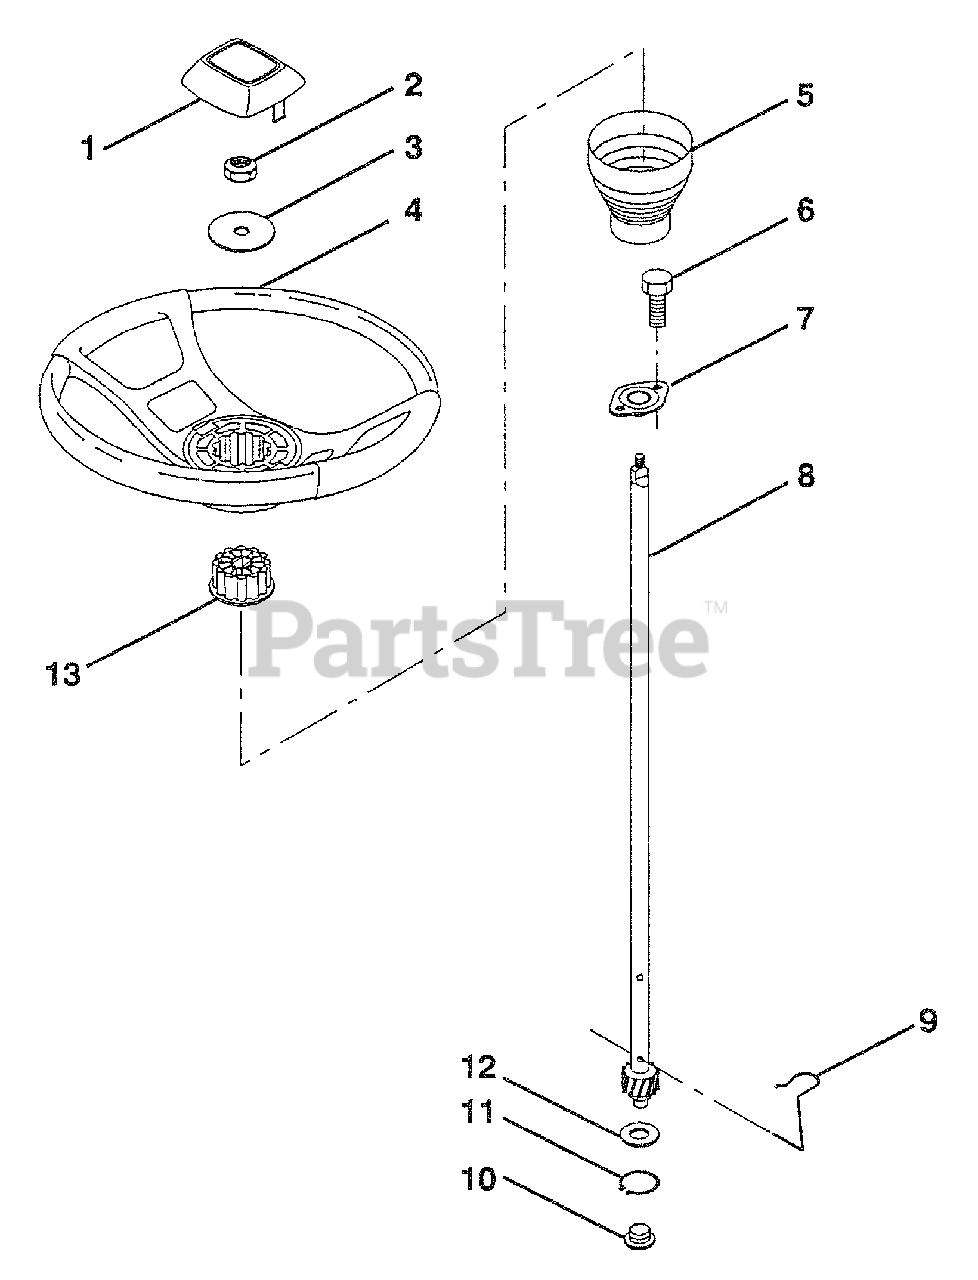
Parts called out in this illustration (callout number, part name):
1	Insert, Wheel, Steering
2	Nut, Lock 3/8-24 UNF
3	Washer 12/32 x 2-3/8 x 8 Ga.
4	Wheel, Steering
5	Sleeve, Steering
6	Screw, Flex #10-16 x 1/2 TY-B
7	Bushing, Steering
8	Shaft, Steering
9	Clip, Steering
10	Bushing, Lower, Steering
11	Ring, Retaining
12	Washer 21/32 x 1 x 16 Ga.
13	Adaptor, Wheel, Steering
